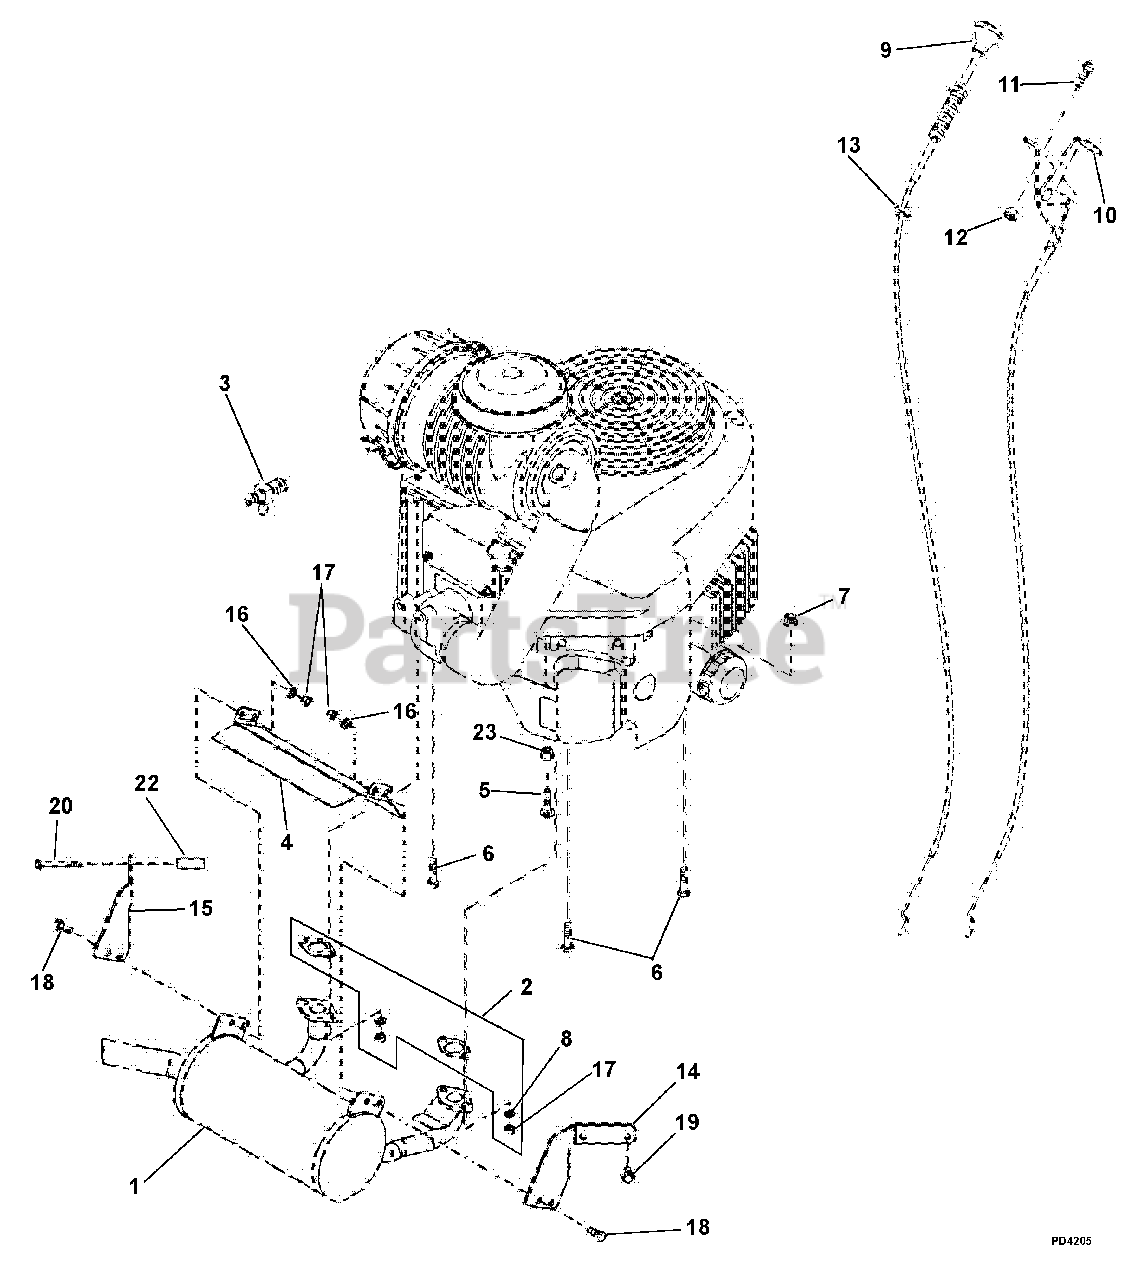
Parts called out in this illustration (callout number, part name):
1	Muffler
2	Gasket Kit, (Includes Gaskets, items 8 and 17)
3	Oil Drain Fitting
4	Muffler Shield
5	Carriage Bolt, Engine Mounting M8 x1
6	Cap Screw, Engine Mounting M8 x 1.2
7	Nut, Locking, Nylon M8-1.25
8	Washer, Lock .31 x .078
9	Cable, Choke
10	Cable, Throttle
11	Bolt, Hex, 8-32 x .5
12	Nut, Locking, Nylon 8-32 With Insert
13	Nut, Hex .38-16
14	Bracket, Muffler Support RH
15	Bracket, Muffler Support LH
16	Washer, Helical Spring
17	Nut, Hex, M8-1.25
18	Bolt, Hex, M8-1.250 x 20
19	Bolt, Hex, M8 x 1.25 x 16
20	Screw, Flanged Metric M6 x 60
21	Shield, Heat
23	Bolt, Hex, M8 x 1.25 x 16
